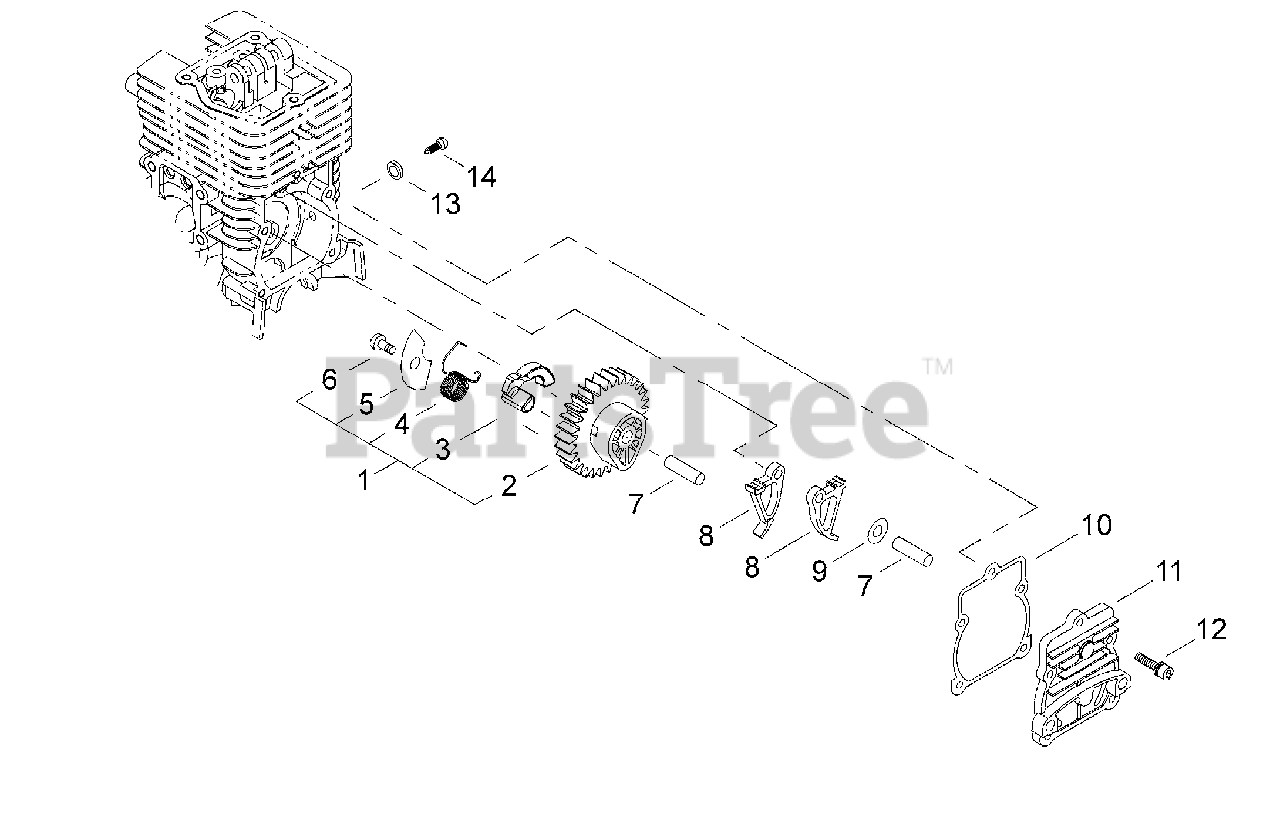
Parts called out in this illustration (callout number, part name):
1	CAM GEAR ASSY
2	GEAR, CAM
3	WEIGHT
4	SPRING
5	COVER, PLATE
6	SCREW - 4X6 -- TAPPING
7	PIN - LOCATING
8	FOLLOWER, CAM
9	WASHER - 5
10	GASKET
11	COVER, CAM GEAR
12	SCREW - 4X14
13	WASHER
14	SCREW - 5
